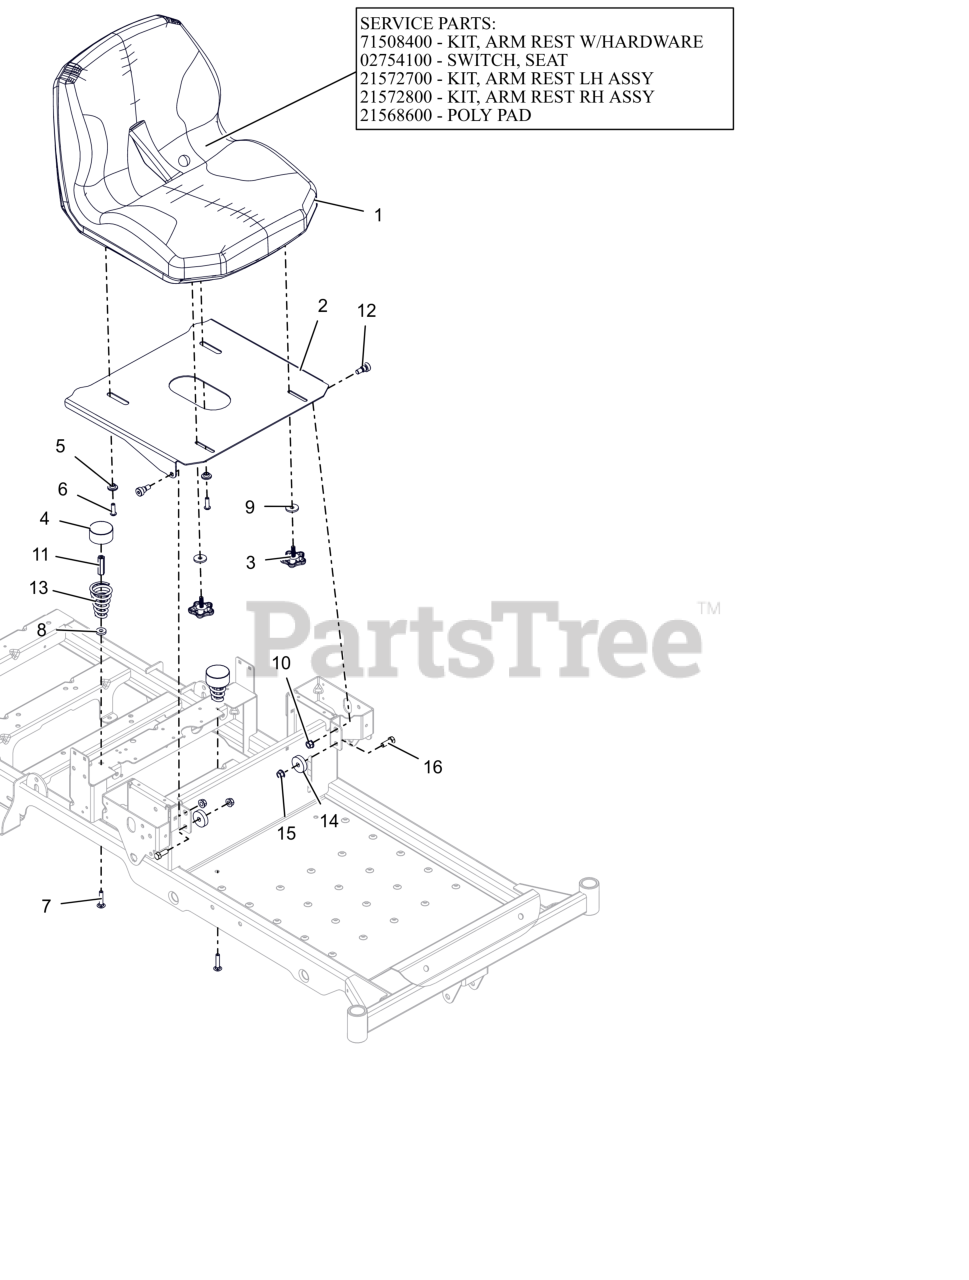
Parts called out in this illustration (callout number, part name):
1	SEAT, EDGE 2020
1	KIT, ARMREST - EDGE
1	SWITCH- SNAP MTG N.O.
1	KIT, ARM REST LH ASSY - PADDED
1	KIT, ARM REST RH ASSY - PADDED
1	POLY PAD
2	PLATE, SEAT (ORANGE)
3	KNOB, WING STUDDED
4	HUB CAP
5	BSHG-FLG .32X.500X.344X.880
6	BLT,SHCS-BTN .31-18X1.00 ZCC
7	BLT,RHSN .31-18X1.50 G5 ZCC
8	WSHR, FLT .328X.870X.179 ZCC
9	WSHR, FLT .340X1.125X.135 ZCC
10	NUT-LK-TOP-FLG .38-16 ZC120
11	NUT, COUPLING .31-18X1.75 ZCC
12	BLT-SHLDR .38-16X.38 SKH
13	SPRING, SEAT
14	SPACER, .39 X 1.50 X .380
15	NUT-LK-CTR-FLG .375-16 GF ZCC
16	BLT,HEX .38-16X1.00 G5 ZCC
